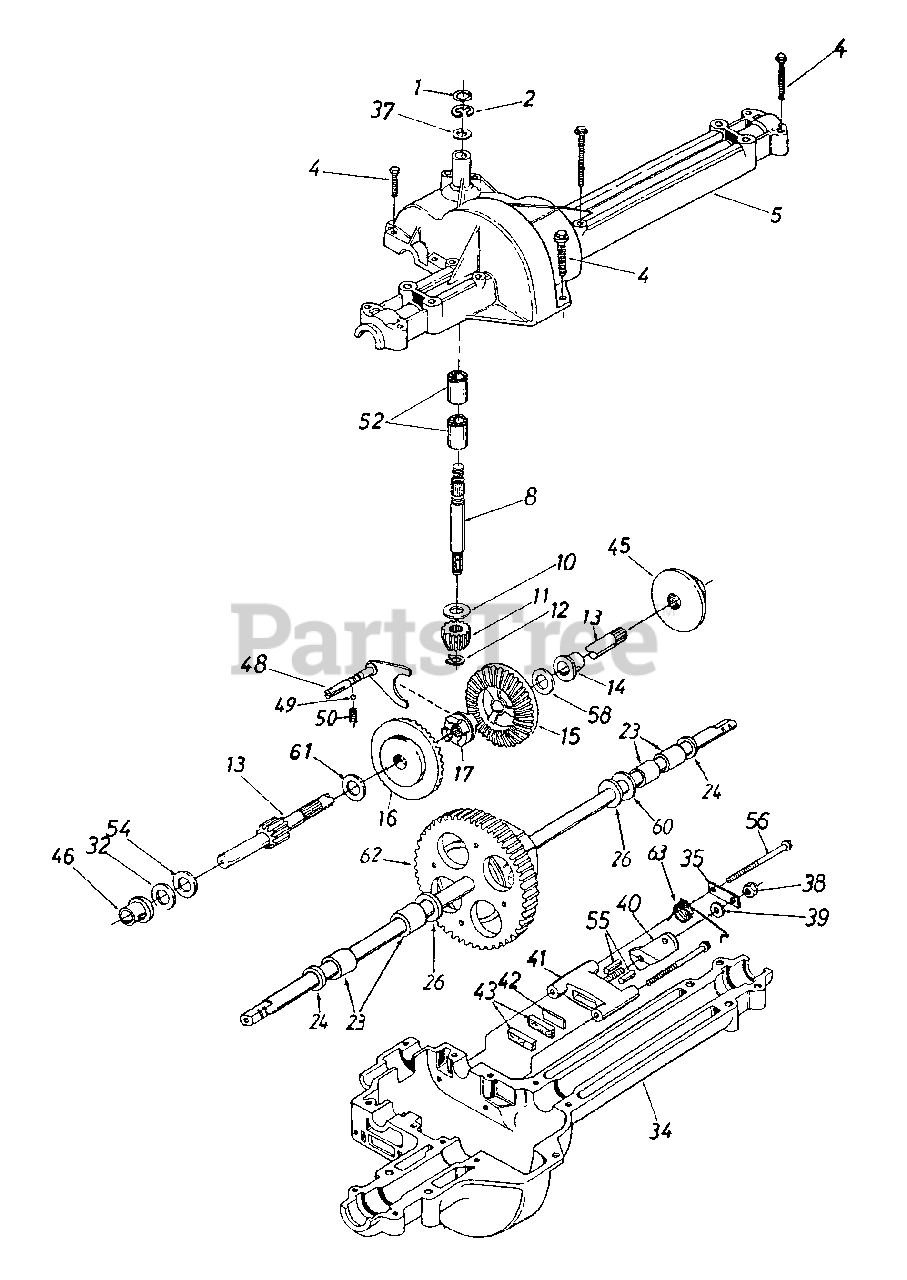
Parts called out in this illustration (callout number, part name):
1	Wire Ring
2	E-Ring
4	Hex Tap Scr. 1/4-20 x 1.625 Lg.
5	Upper Housing
8	Input Shaft
10	Thrust Washer 5/8" I.D. x1.25" O.D.
11	Pinion Input 14T
12	Retaining Ring
13	Drive Shaft-R.H. Brake
14	Flange Brg. 5/8" I.D. x 3/4" Lg.
15	Bevel Gear 42T Small I.D.
16	Bevel Gear 42T Large I.D.
17	Clutch Collar
23	Sleeve Bearing 3/4" I.D. x1.0" Lg.
24	Oil Seal 3/4" I.D.
26	Fl-Wash. .760" I.D. x 1.5" O.D.
32	Thrust Wash. 5/8" I.D. x 1" O.D. x .025" Thk.
32	Fl-Wash. 5/8" I.D. x 1" O.D. x .030" Thk.
32	Thrust Wash. 5/8" I.D. x 1" O.D. x .035" Thk.
32	Fl-Wash. 5/8" I.D. x 1" O.D. x .040" Thk.
34	Lower Housing
35	Anti-Rotation Brkt.
37	Fl-Wash. 5/8" I.D. x 1" O.D. x .020" Thk.
37	Fl-Wash. 5/8" I.D. x 1" O.D. x .030" Thk.
37	Fl-Wash. 5/8" I.D. x 1" O.D. x .040" Thk.
38	Hex Nut 5/16-24 Thd.
39	Fl-Wash. .344" I.D. x .875" O.D.
40	Actuating Arm
41	Brake Yoke
42	Puck Plate
43	Brake Puck
45	Brake Disc
46	Flange Bearing 5/8" I.D. x 15/16" Lg.
48	Shift Fork Ass'y.
49	Ball Detent .250" Dia.
50	Spring Detent
52	Needle Brg. 5/8" I.D. x 1/2" Lg.
54	Fl-Wash. 5/8" I.D. x 1" O.D.x .020 Thk.
55	Actuating Pin 5/16" Dia.
56	Hex Wash Hd. Self-Tap Scr.1/4-20
58	Fl-Wash. 5/8" I.D. x 1" O.D. x.020 Thk.
58	Thrust Wash. 5/8" I.D. x 1" O.D. x .025"
60	Fl-Wash. .76" I.D. x 1.5" O.D. x .010" Thk.
60	Fl-Wash. .76" I.D. x 1.5" O.D. x .020" Thk.
60	Fl-Wash. .76" I.D. x 1.5" O.D. x .030" Thk.
60	Fl-Wash. .76" I.D. x 1.5" O.D. x .060" Thk.
61	Thrust Washer
62	Differential Ass'y.
63	R.H.-Brake Spring
